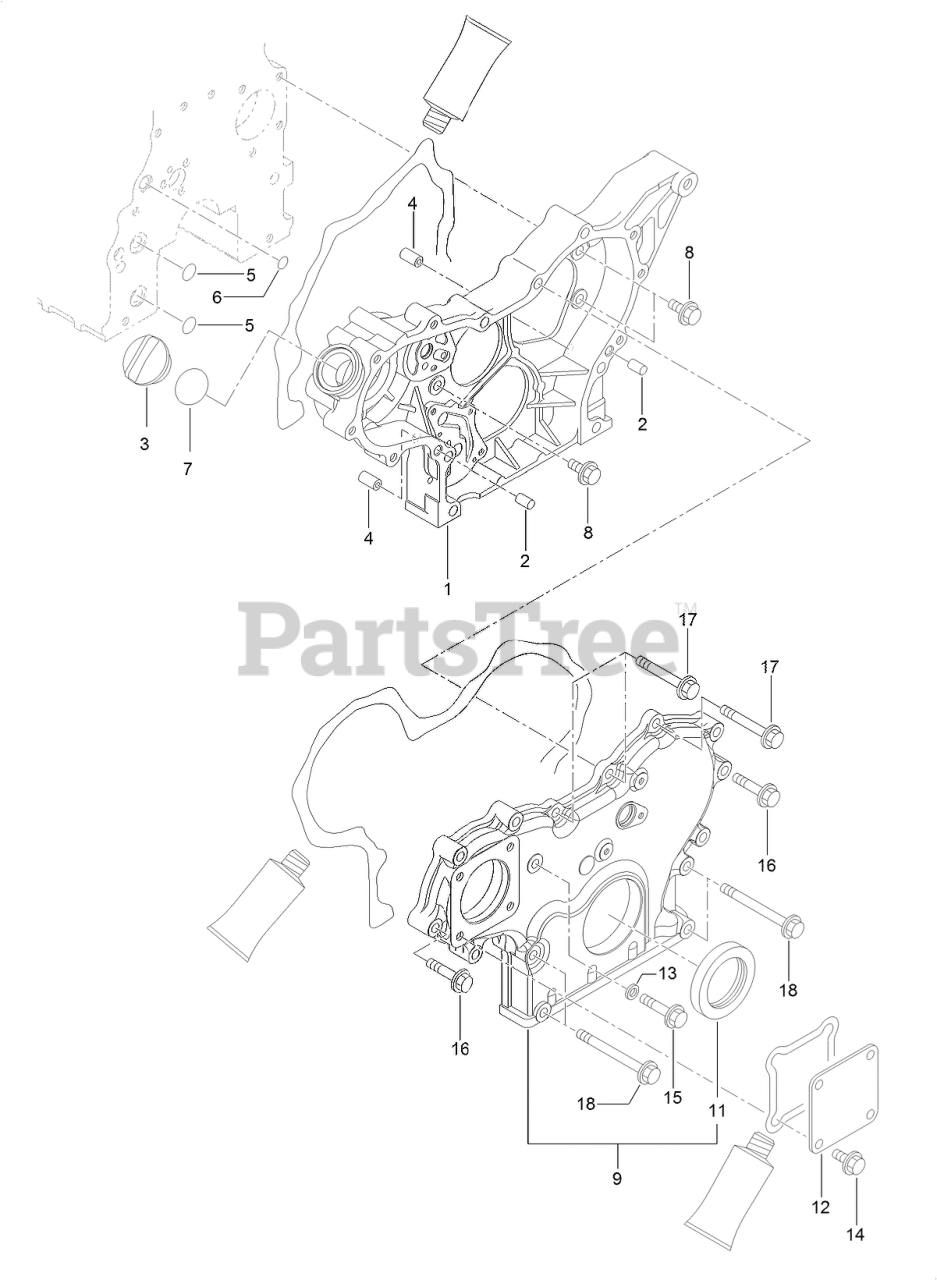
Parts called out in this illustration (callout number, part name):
1	Case-Gear
3	COVER-FILLER
8	BOLT
9	GEARCASE COVER ASM
11	SEAL-OIL
13	WASHER-SEAL
14	BOLT
